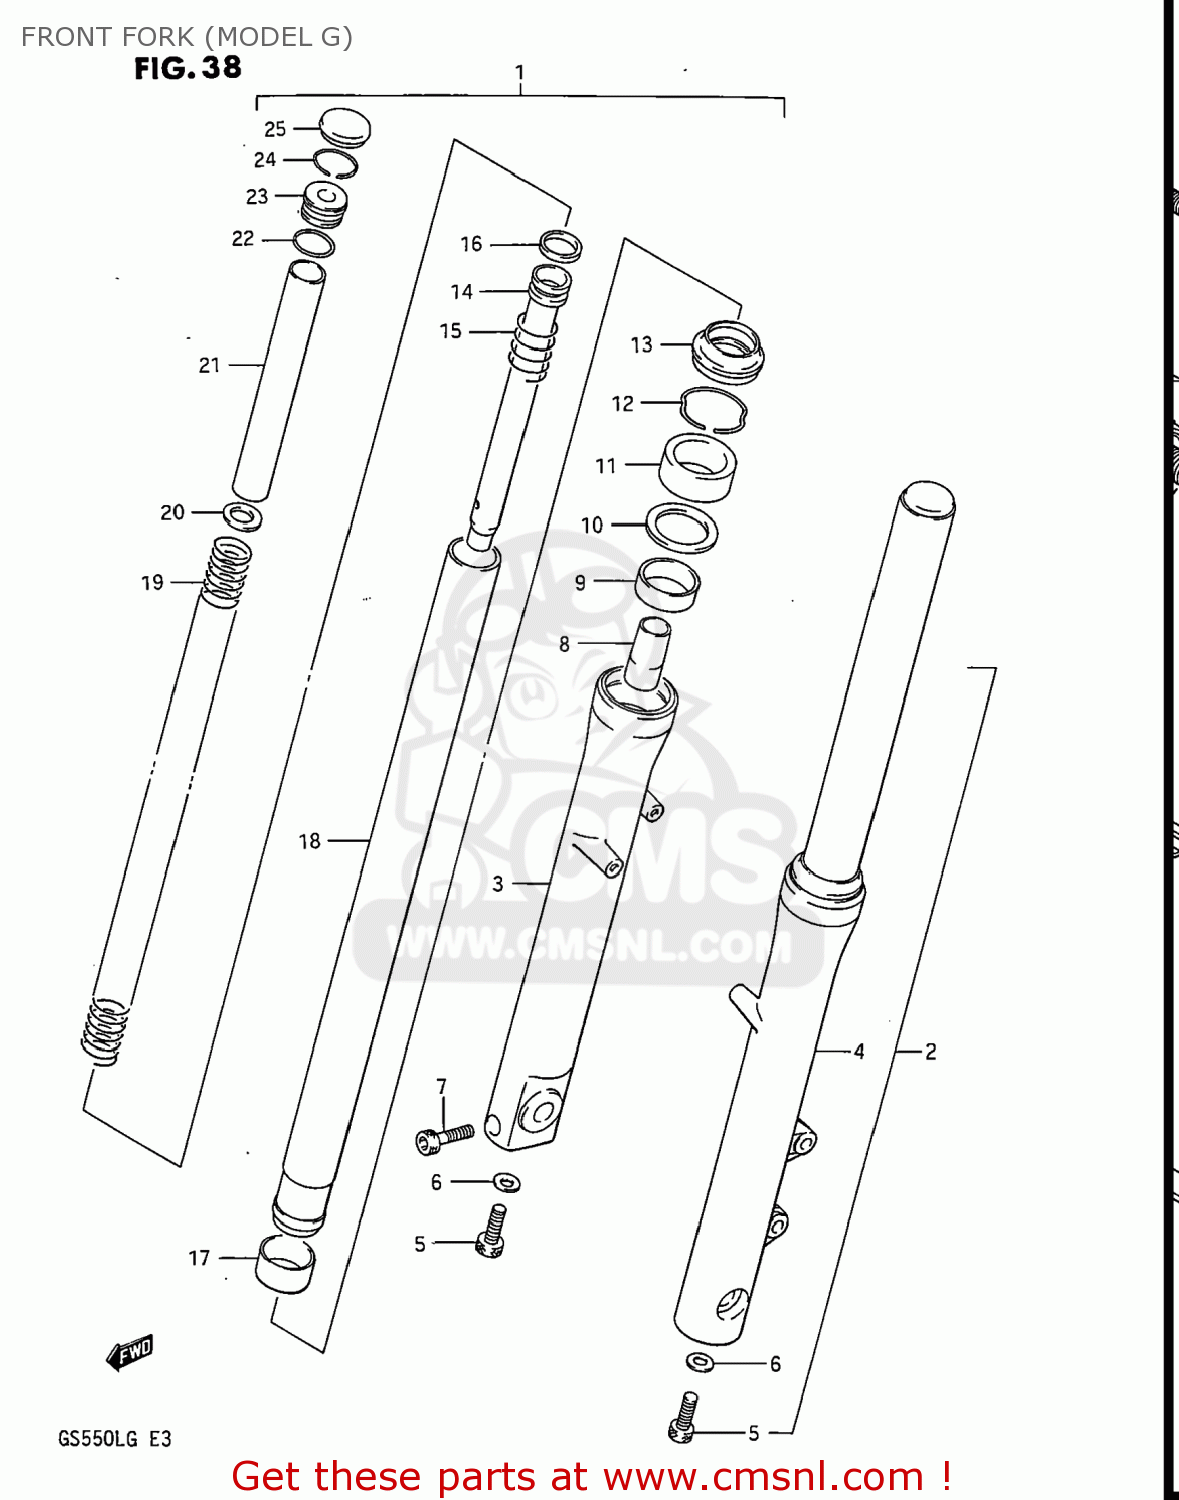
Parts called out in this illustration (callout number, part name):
1	DAMPER ASSEMBLY,RIGHT
2	DAMPER ASSEMBLY,LEFT
3	TUBE,OUTER,RIGHT
4	TUBE,OUTER,LEFT
5	BOLT(8X27)
6	GASKET (NAS)
7	BOLT, FRONT RH
8	PIECE,OIL LOCK
9	BUSH,GUIDE
10	SPACER,SEAL
11	OIL SEAL,FRONT FORK 35X48X11
12	CIRCLIP,FORK OIL SEAL
13	SEAL,DUST
14	CYLINDER
15	SPRING,REBOUND
16	RING,FRONT FORK PISTON
17	PISTON
18	TUBE,FORK,INNER
19	SPRING
21	SPACER,SPRING
22	O RING
23	SPRING SEAT B
24	RING,STOPPER
25	CAP
